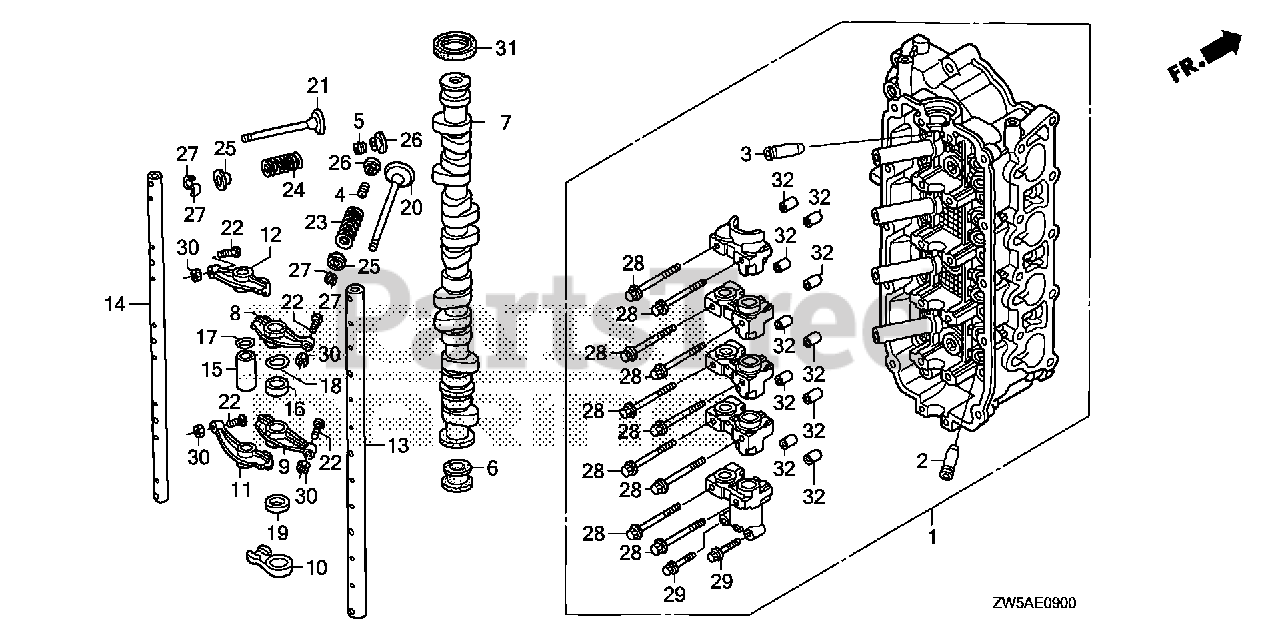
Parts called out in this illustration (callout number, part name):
1	CYLINDER HEAD SUB-ASSY. *NH8* (DARK GRAY)
2	GUIDE, VALVE (OVER SIZE)
3	GUIDE, EX. VALVE (OVER SIZE)
4	SEAL A, VALVE STEM (NOK)
5	SEAL B, VALVE STEM (NOK)
6	RUBBER, CYLINDER HEAD SEAL
8	ARM A, IN. ROCKER
9	ARM B, IN. ROCKER
10	ARM, FUEL PUMP ROCKER
11	ARM A, EX. ROCKER
12	ARM B, EX. ROCKER
13	SHAFT, IN. ROCKER ARM
14	SHAFT, EX. ROCKER ARM
15	COLLAR, ROCKER (A)
16	COLLAR, ROCKER (B)
17	WASHER, WAVE
18	WASHER, IN. WAVE
19	COLLAR A, IN. ROCKER
20	VALVE, IN. (TMSS)
21	VALVE, EX. (TMSS)
22	SCREW, TAPPET ADJUSTING
23	SPRING, IN. VALVE (ORANGE) (NHK SPRING)
24	SPRING, EX. VALVE (VIOLET) (CHUO SPRING)
25	RETAINER, VALVE SPRING
26	SEAT, VALVE SPRING
27	COTTER, VALVE (FUJI VALVE)
28	BOLT, FLANGE (8X76)
29	BOLT, FLANGE (6X40)
30	NUT, TAPPET ADJUSTING
31	OIL SEAL (35X50X8) (NOK)
32	PIN, DOWEL (10X16)
